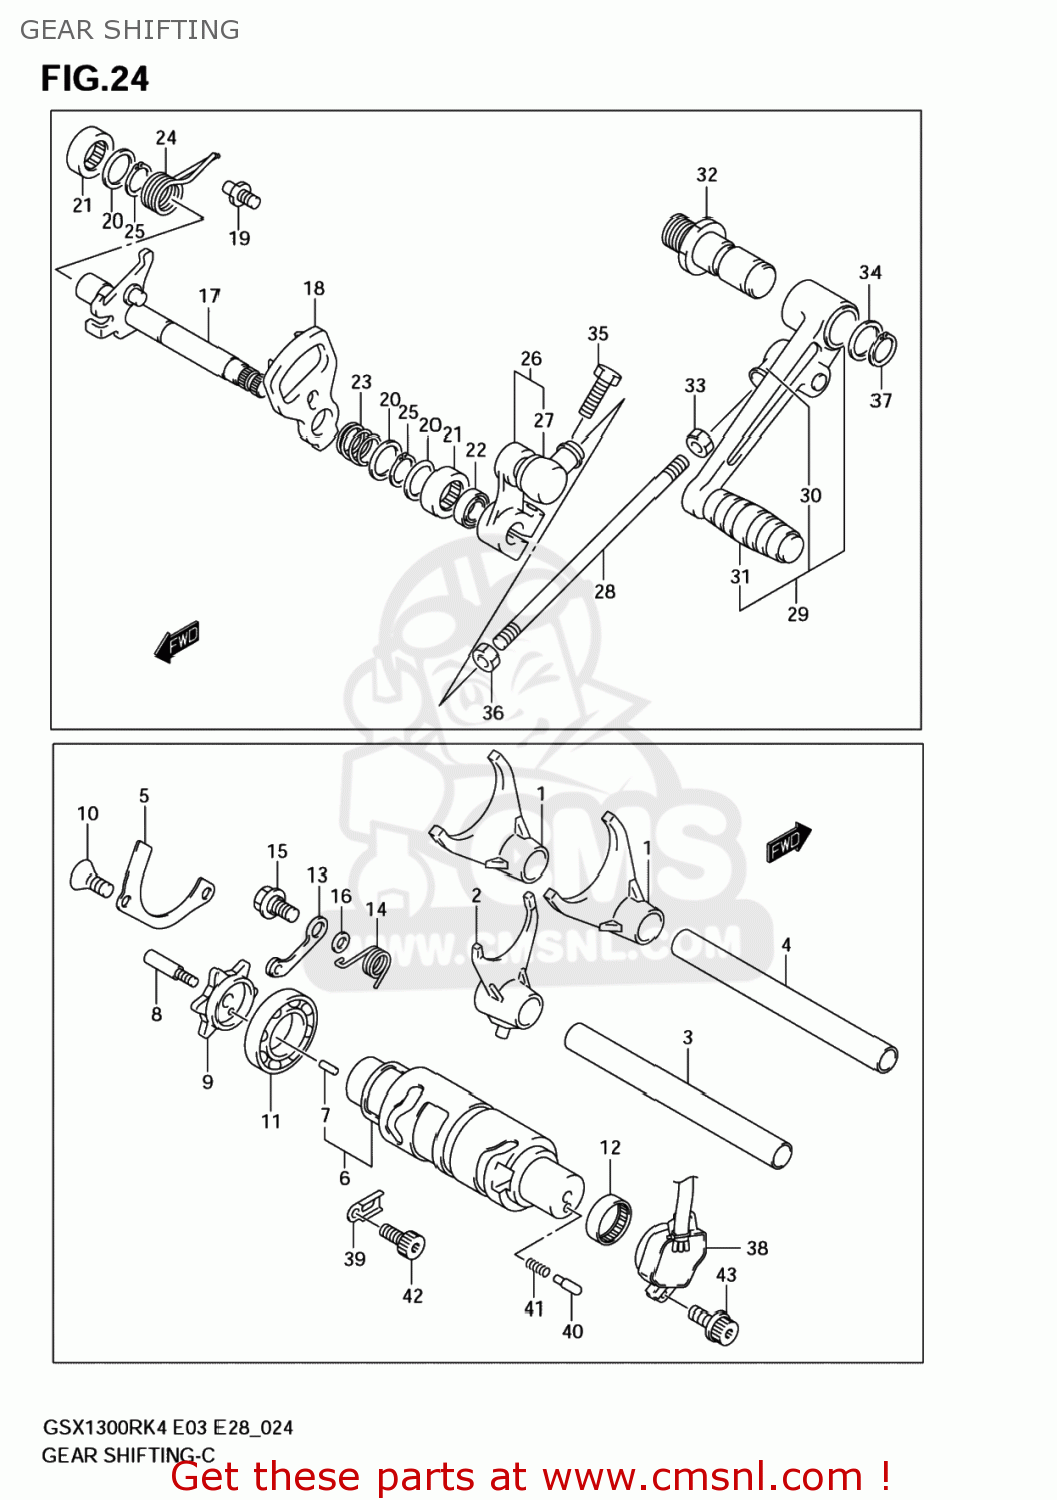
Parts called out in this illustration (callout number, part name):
1	FORK,GEAR SHIFT NO.1
2	FORK,GEAR SHIFT NO.3
3	SHAFT,SHIFT FORK NO.2(L:132)
4	SHAFT,GEAR SHIFT FORK(L:152)
5	RETAINER,SHIFT CAM BEARING
6	CAM,GEAR SHIFT
7	PIN
8	BOLT,GEAR SHIFT CAM PL
9	PLATE,GEAR SHIFT CAM
10	SCREW(6X12)
11	BEARING(25X47X8)
12	BEARING(25X32X12)
13	STOPPER,SHIFT CAM
14	SPRING,STOPPER ARM
15	BOLT(6X14.3)
16	WASHER
17	SHAFT,GEAR SHIFT
18	PLATE,GEAR SHIFT CAM DRIVE
19	STOPPER,GEAR SHIFT ARM
20	SHIM(14X22X1)
21	BEARING(14X20X12)
22	SEAL,OIL(14X22X6)
23	SPRING
24	SPRING
25	CIRCLIP
26	ARM,GEAR SHIFT LINK
27	COVER,DUST
28	ROD,GEAR SHIFT LINK
29	LEVER ASSY,GEAR SHIFT
30	COVER,DUST
31	RUBBER,GEAR SHIFT PEDAL
32	SHAFT,GEAR SHIFT LEVER
33	NUT
34	WASHER(12.5X20X1)
35	BOLT
36	NUT
37	CIRCLIP,12 MM
38	BASE ASSY,GEAR SHIFT TERMINAL
39	CLAMP,GENERATOR LEAD WIRE
40	PIN(5X15.5)
41	SPRING
42	BOLT
43	BOLT
